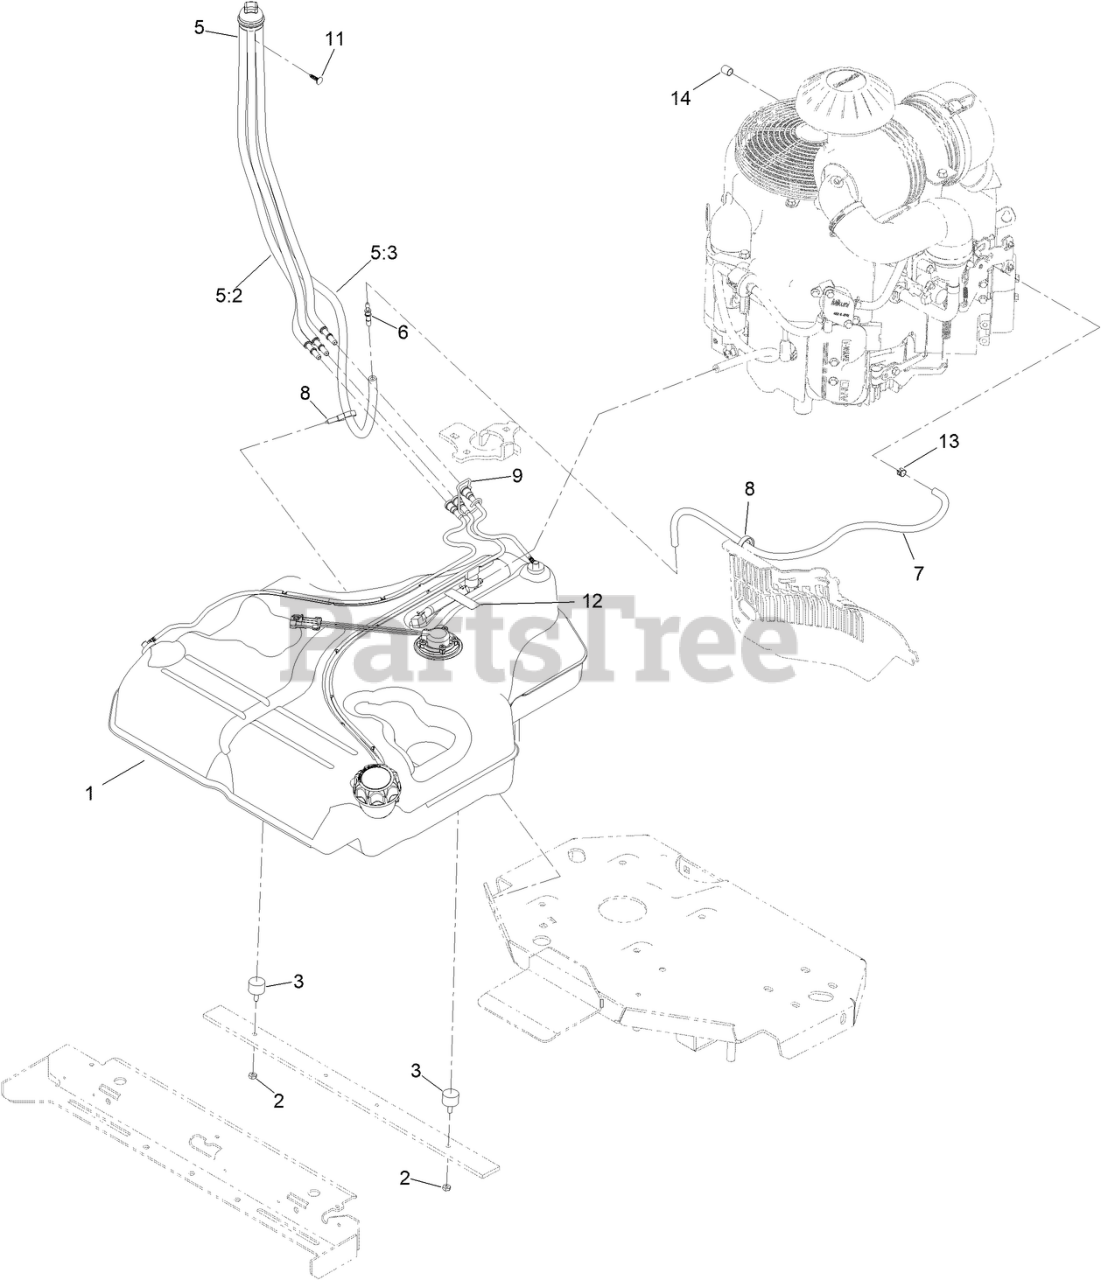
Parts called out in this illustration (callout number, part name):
1	FUEL TANK ASM
2	NUT-JAM
3	BUMPER
5	FUEL MANIFOLD VENT ASM
5:2	HOSE-FUEL
5:3	HOSE-FUEL
6	BARB-FUEL
7	HOSE-FUEL
8	CLAMP-HOSE
9	RETAINER-LINE, VAPOR
11	PLUG-PLASTIC
12	DECAL-STRIP BLACK
13	CLAMP-HOSE
14	PLUG-PORT
